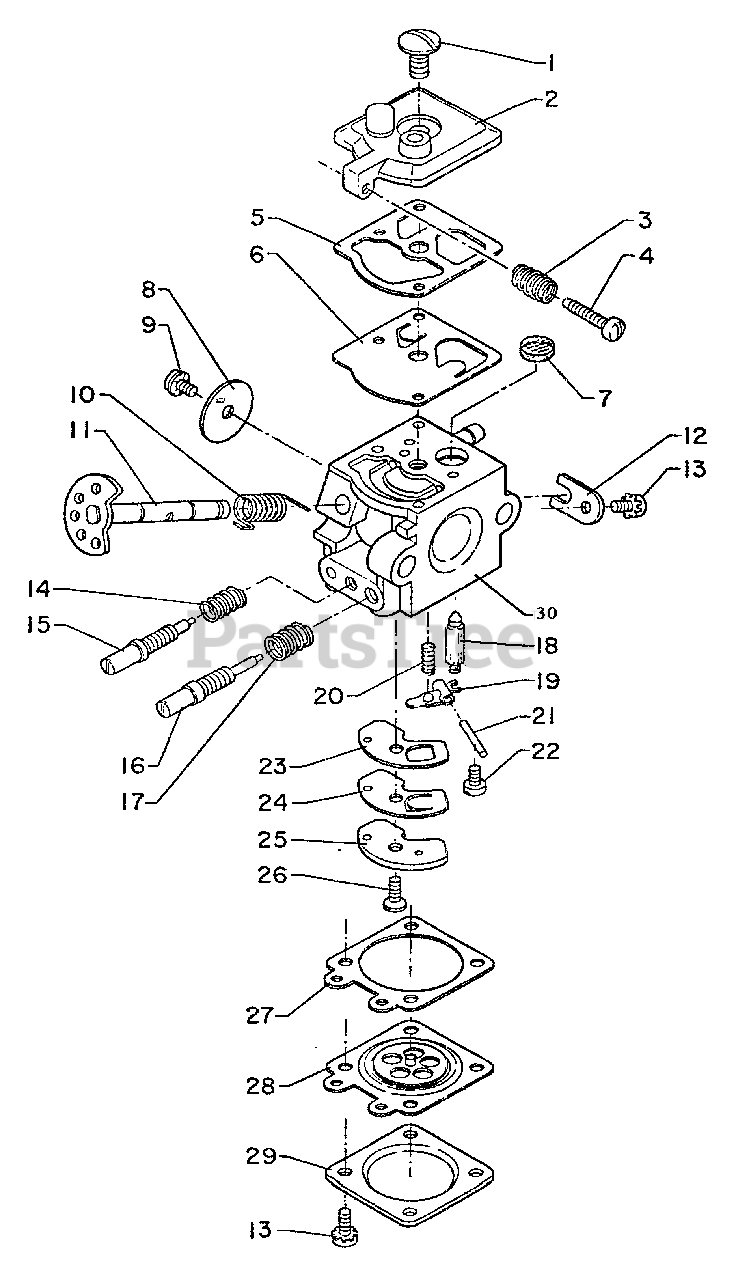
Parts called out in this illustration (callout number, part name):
1	SCREW, PUMP COVER
2	COVER, PUMP
3	SPRING, IDLE ADJUST
4	SCREW, IDLE ADJUST
5	GASKET, PUMP
6	DIAPHRAGM, PUMP
7	STRAINER
8	VALVE, THROTTLE
10	SPRING, THROTTLE RETURN
11	SHAFT, THROTTLE
12	CLIP, THROTTLE SHAFT
14	SPRING, IDLE ADJUST
15	NEEDLE - LOW SPEED
16	NEEDLE - HIGH SPEED
18	VALVE, INLET NEEDLE
19	LEVER, METERING
20	SPRING, METERING LEVER
21	PIN, METERING LEVER
22	SCREW, METERING LEVER PIN
23	GASKET, CIRCUIT PLATE
24	VALVE, CHECK
25	PLATE, CIRCUIT
26	SCREW, CIRCUIT PLATE
27	GASKET, METERING
28	DIAPHRAGM, METERING
29	COVER, METERING
30	BODY, CARBURETOR
